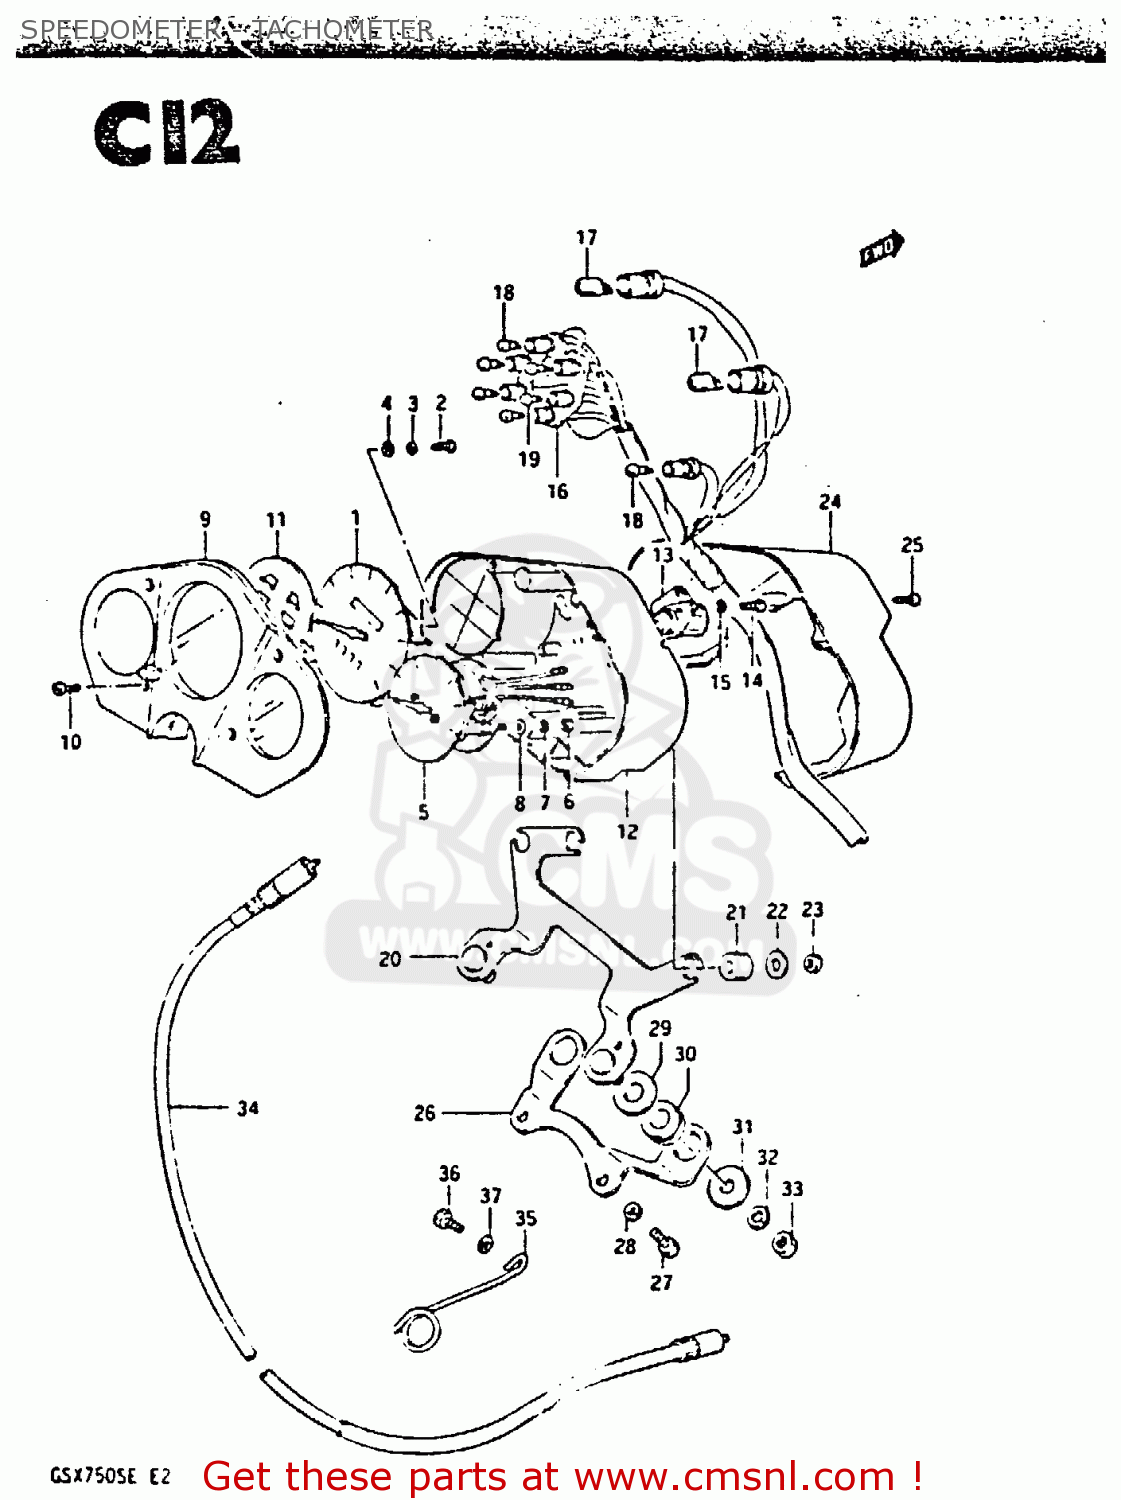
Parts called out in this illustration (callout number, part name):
1	2
2	SCREW
3	LOCK WASHER
4	WASHER 3.3X8X0
5	TACHOMETER
6	NUT
7	LOCK WASHER
8	WASHER
9	HOOD,METER
10	SCREW
11	PLATE, PILOT LENS
12	CASE, METER
13	GEAR BOX,SPEEDOMETER
14	SCREWM4X0.7X10
15	LOCK WASHER
16	SOCKET, METER
17	BULB(12V3.4W,T10,BF175-01450A)
18	BULB(12V3W,WB371,T7)
19	BULB(12V1.7W,WB372,T7)
20	BRACKET, METER
21	CUSHION,METER
22	WASHER,METER
23	NUT
24	COVER, LOWER
25	SCREW
26	BRACKET, METER
27	BOLT 6X16
28	WASHER,LOCK
29	WASHER (12.5X26X1.6)
30	CUSHION
31	WASHER (8.5X20X1.6)
32	WASHER,LOCK,8.
33	NUT
34	CABLE ASSY,SPEEDOMETER
35	CLAMP,SPEEDOMETER CABLE
36	BOLT, UPPER
37	WASHER
